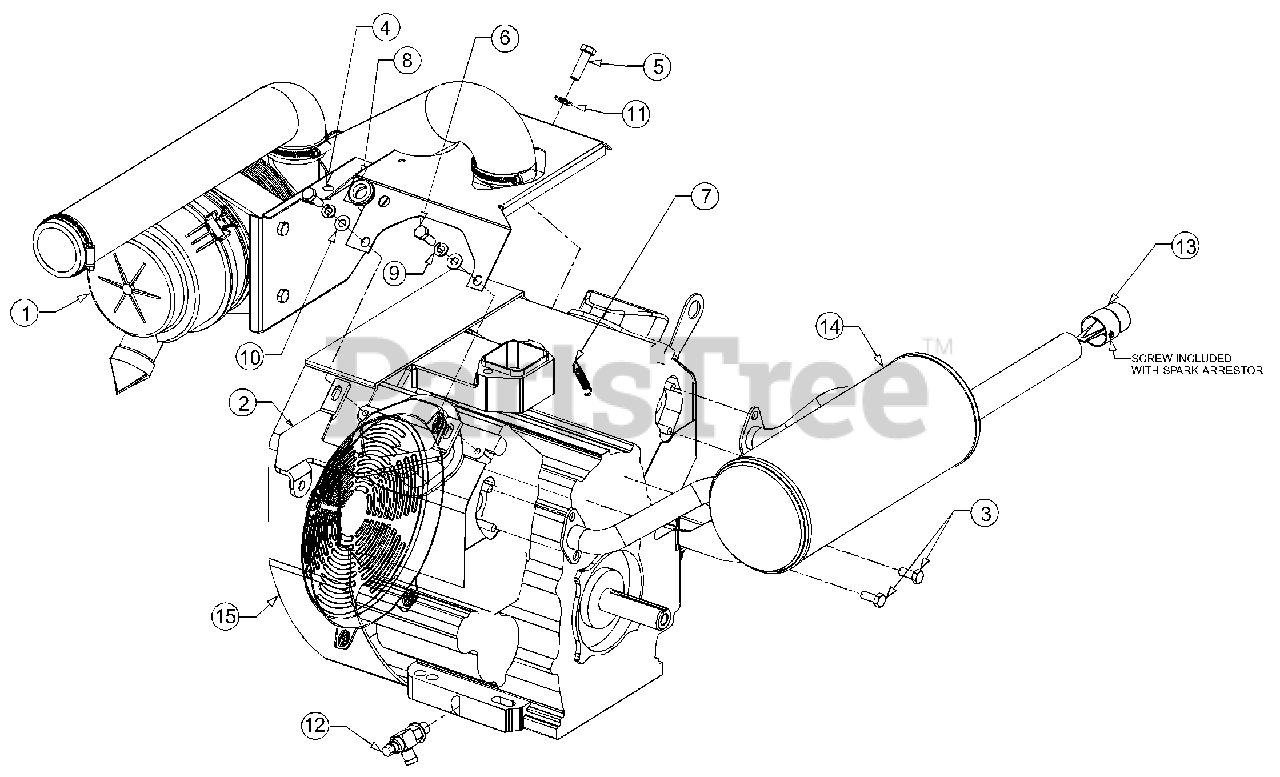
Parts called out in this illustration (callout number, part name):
1	Filter Assembly, Air Cleaner
2	Support, Upper Transmission
3	Hex Screw, M8-1.25
4	Screw, Machine #10-24 x .50
5	Hex Screw, 3/8-16 x 1.25
6	Hex Screw, M8-1.25 x 25, Gr8
7	Spring, Extension, .315 OD x 2.125
8	Grommet, Rubber .66 ID x 1.25 OD
9	Washer, Lock, 5/16
10	Washer, Flat, .33 x .678 x .030
11	Washer, Flat, .406 x .812 x .051
12	Valve, Oil Drain
13	Arrestor, Spark 1-1/4
14	Muffler, Honda GXV
15	Engine, Honda GX620K1
